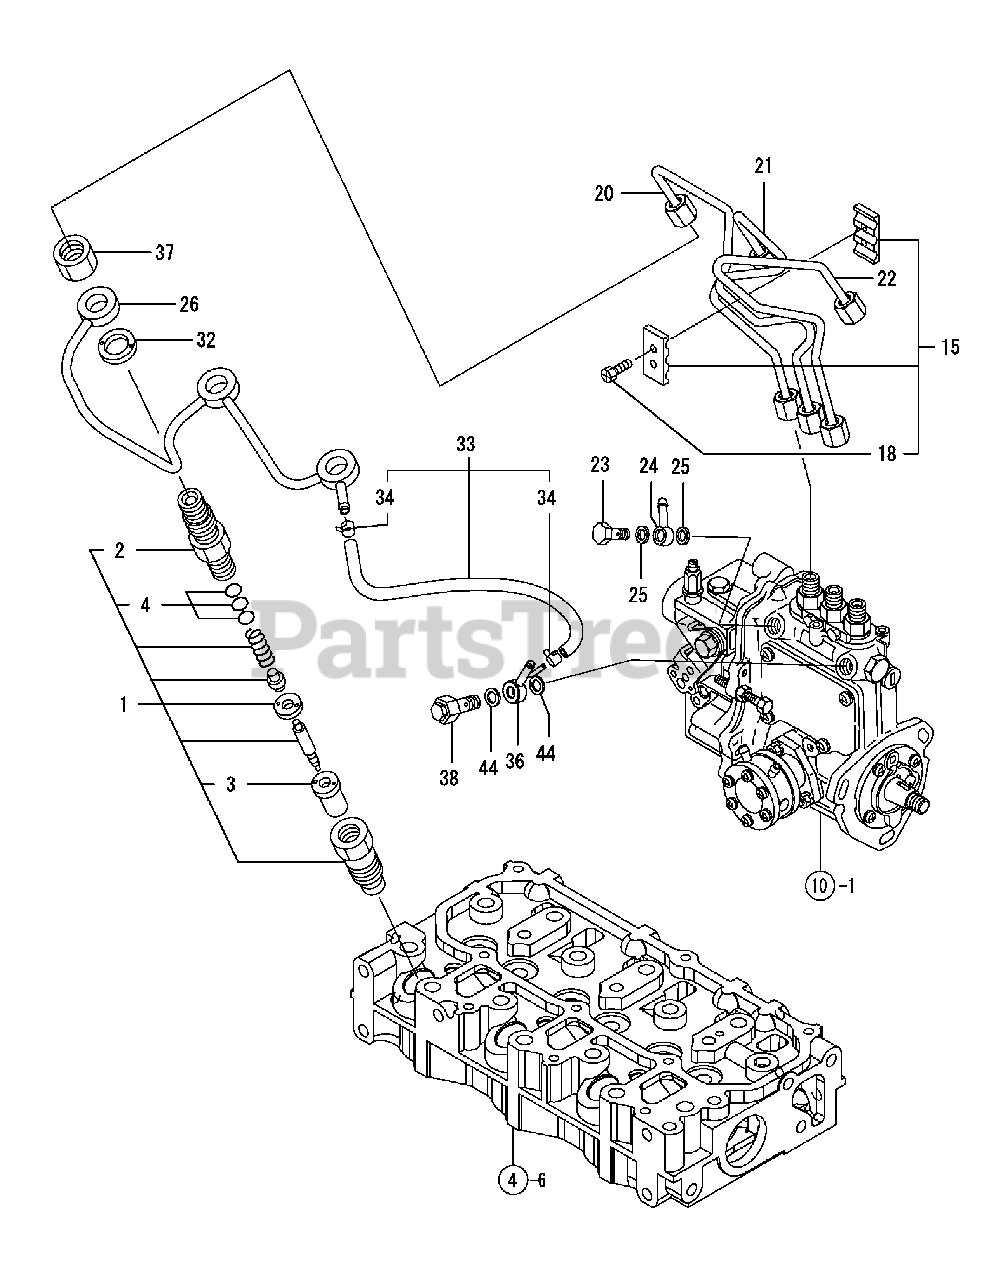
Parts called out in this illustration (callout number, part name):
1	Valve Assembly, Injection
2	Holder, Nozzle
3	Nozzle Assembly
15	Retainer, Inj. Pipe
18	Bolt, M 4 x 14, Hex Sckt.
20	Pipe, Fuel Injection
21	Pipe, Fuel Injection
22	Pipe, Fuel Injection
23	Bolt, Pipe Joint
24	Joint 12, Pipe
25	Seal Washer 12
26	Pipe Assembly, Return
32	Gasket, Return
33	Pipe, Fuel Return
38	Valve Assembly, Check
